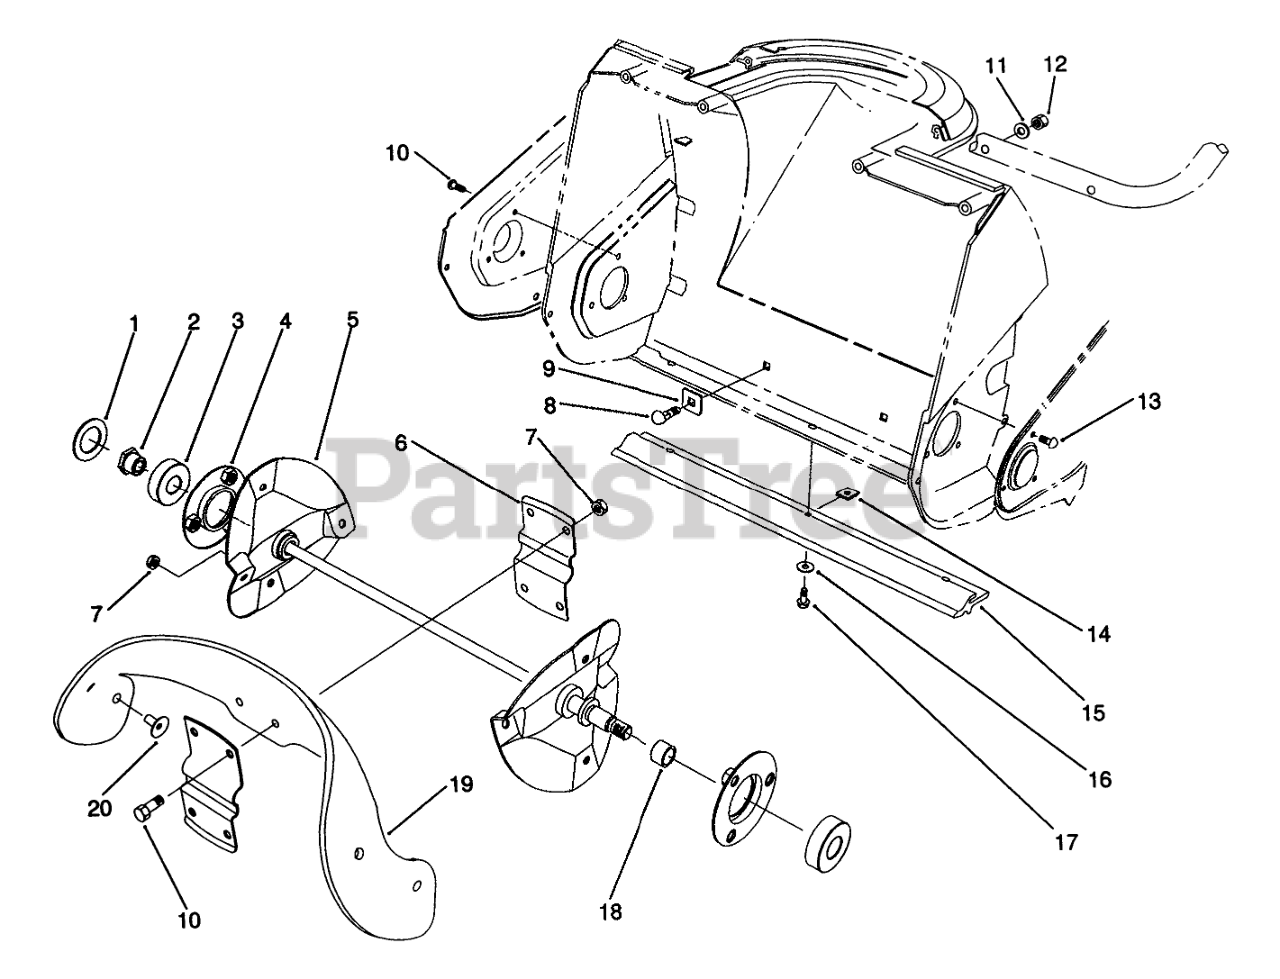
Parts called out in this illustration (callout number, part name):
1	WASHER-RUBBER
3	BEARING-BALL
4	FLANGE BEARING ASM
5	Rotor
6	Support-Rotor
7	NUT-LOCK, NI
8	SCREW-CARR
9	WASHER-SQUARE
10	SCREW-HHF
11	WASHER
12	NUT-LOCK, NI
13	SCREW-HH
14	"U" TYPE SPEED NUT
15	SCRAPER
16	WASHER-FLAT
17	SCREW-HWHTF
18	SPACER
19	BLADE-ROTOR
20	SCREW
